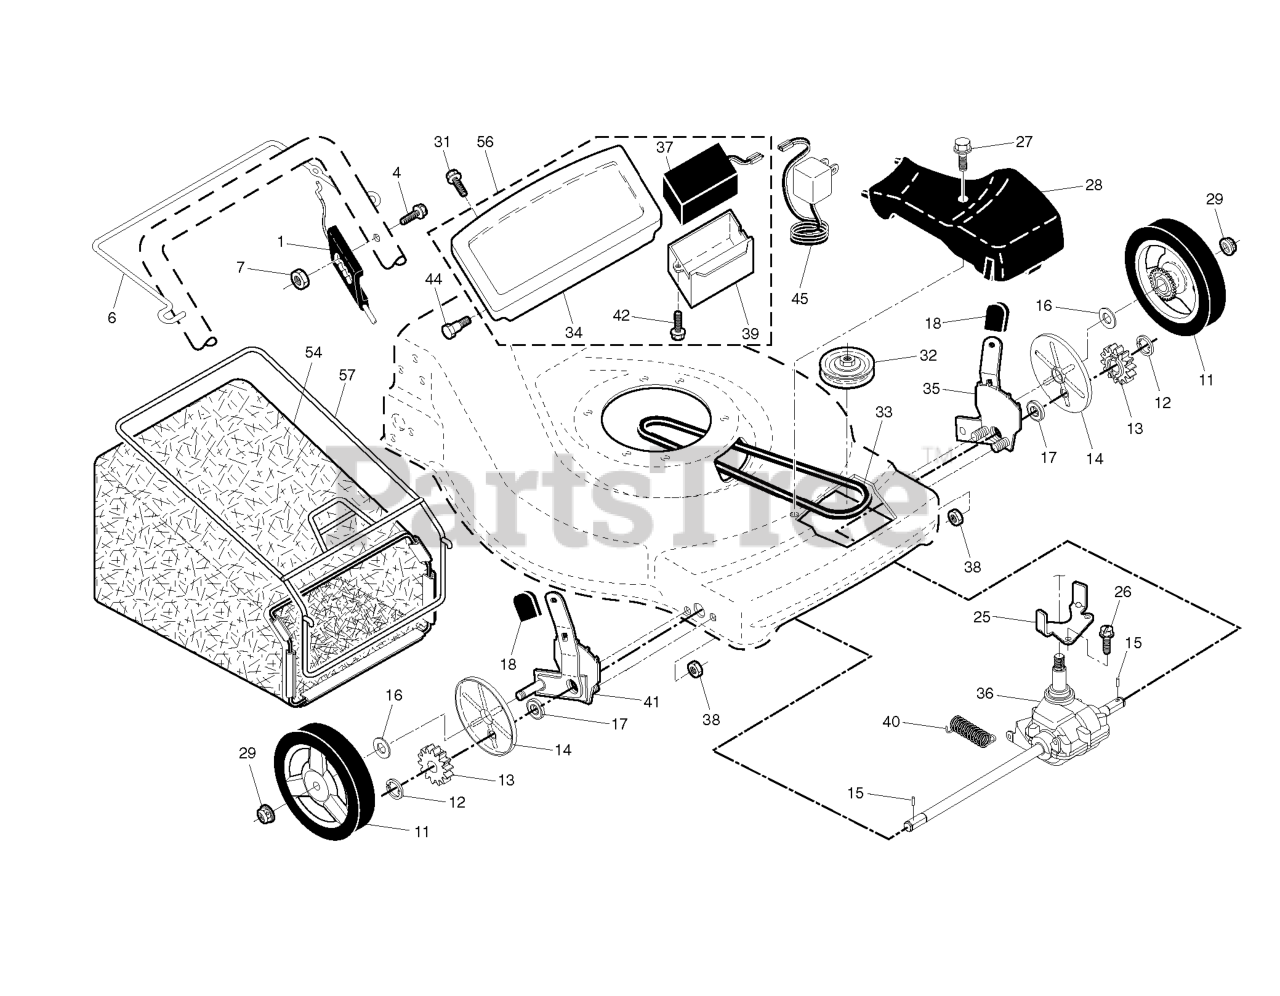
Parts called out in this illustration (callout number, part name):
1	CABLE.DR.VS.BOLT-ON.AUTO.FGD L
6	BAIL.CONT.DR.S/S.ROUND.ORG
7	NUT.HEX.FLANGE.1/4
11	WHEEL.8X1.75.H3SPK.RAD3.GY.BU3
12	E-RING 7/16 RE
13	PINION.14.TEETH.FGD
14	COVER.DUST.WHEEL
15	PAWL, DRIVE
16	WASHER FLUT
17	BEARING
18	SELECTOR KNOB
25	BELT KEEPER
27	SCREW, HEX HD TAPPING #10-24 1
28	RP DRIVE COVER
29	NUT.HEX.FLANGE.3/8-16.LO(3 2)
31	SCREW.PAN.HEAD.#10
32	RP PULLEY.DRIVE.EZ
33	BELT.DRIVE.FG
34	PANEL.TRIM.21.FWGD.ES
35	RP KIT, WHEEL ADJUSTER, LH
36	TRANSMISSION.22.VS.FWGD
37	BATTERY WITH AMP CONECTOR AGM
38	LOCKNUT.NYLOC.1/4-20
39	BOX.BATTERY.TRIM
41	KIT, WHEEL ADJUSTER, RH
42	SCREW.HWH.13-16X.50
44	SCREW.SHOULDER.HH.10X.281X.6
45	RP CHARGER.BATTERY
54	GBAG.83230247T.SIL.HUSQ.BLU
57	FRAME.GBAG.22.EZ.EMPTY.SC
